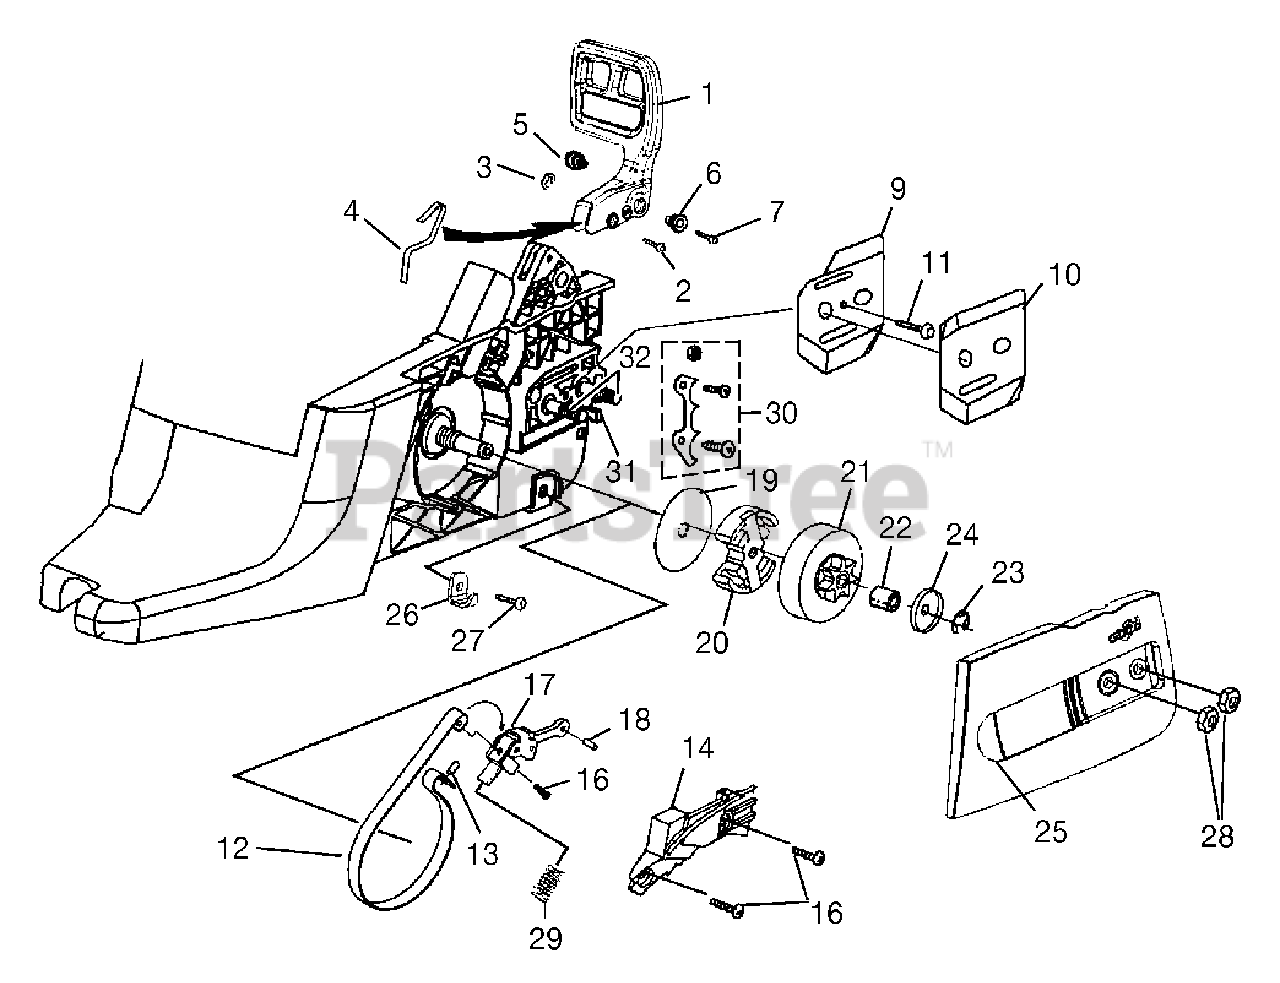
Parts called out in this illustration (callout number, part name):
1	Hand Guard
2	Hand Guard Actuating Pin
3	Retaining Ring
4	Spring, Handguard
5	Pivot, L.H.
6	Pivot, R.H.
7	Screw, Hex Socket Hd. (8-32 x 5/8")
9	Plate, Guide Bar
10	Plate, Guide Bar
11	Screw, Thread Form (6-19 x 1/2")
12	Chain Brake Band
13	Pin, Roll
14	Cover, Chain Brake
16	Screw, Pan Hd. (8-16 x .320)
17	Chain Brake Link
18	Pin, Roll
19	Thrust Washer
20	Clutch & Hardware
21	Sprocket, Drum (.325 Pitch)
22	Bearing, Needle
23	Ring, Retaining
24	Washer, Cupped
25	Drive Case Cover
26	Chain Catcher
27	Screw, Thread Form (10-24 x 1/2")
28	Nut, Hex
29	Spring, Compression
30	Bumper Spike Kit
31	Adjusting Pin (UT10927 and UT10946)
32	Bar Guide Bolt
